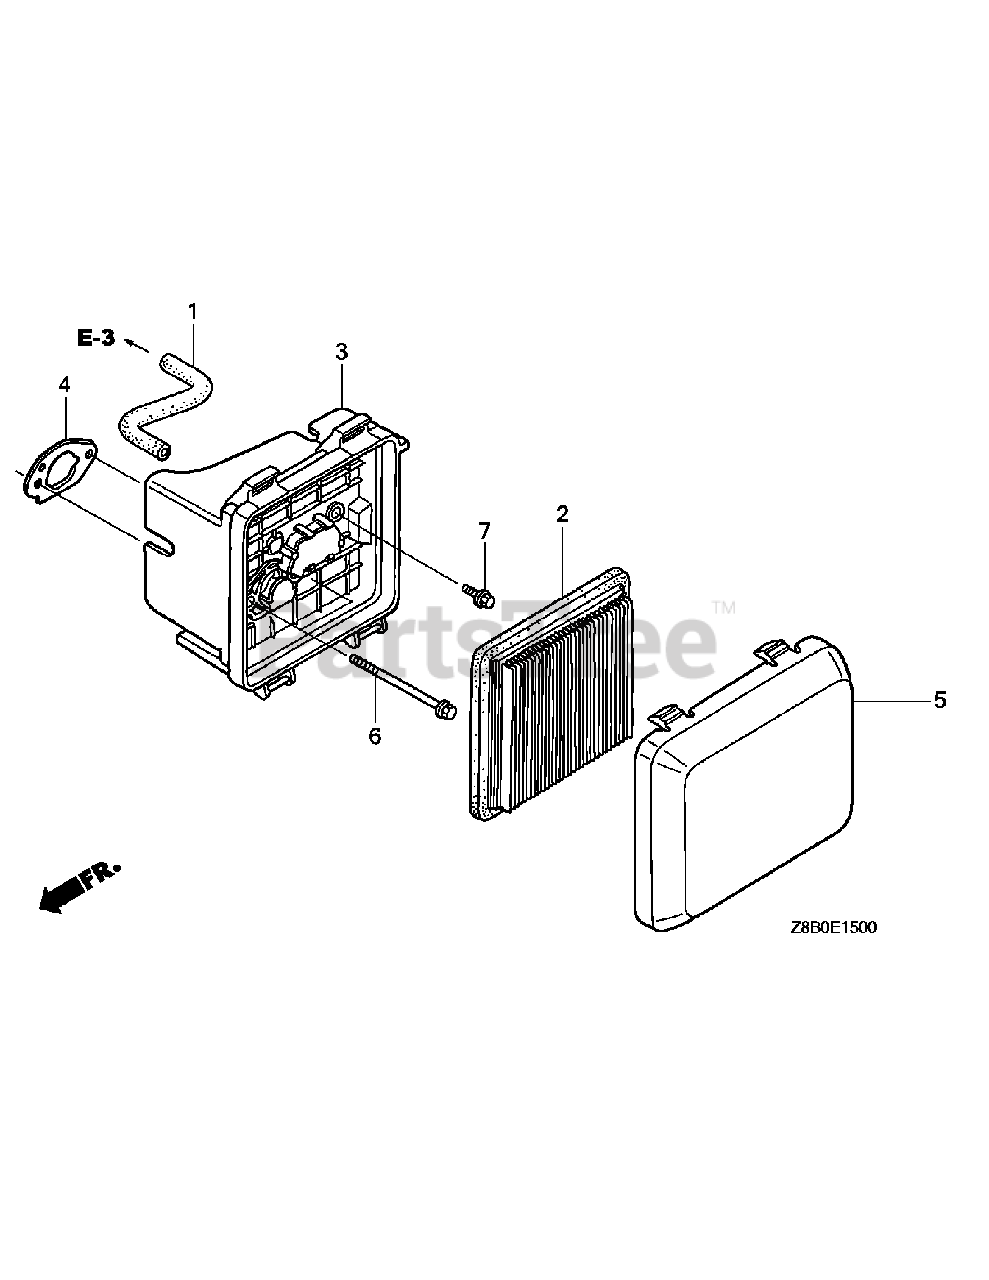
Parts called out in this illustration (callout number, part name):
1	TUBE, BREATHER
2	ELEMENT, AIR CLEANER
3	CASE ASSY., AIR CLEANER
4	PACKING, AIR CLEANER
5	COVER, AIR CLEANER
6	BOLT, FLANGE, 6X86(CT200)
7	BOLT, FLANGE, 6X14
